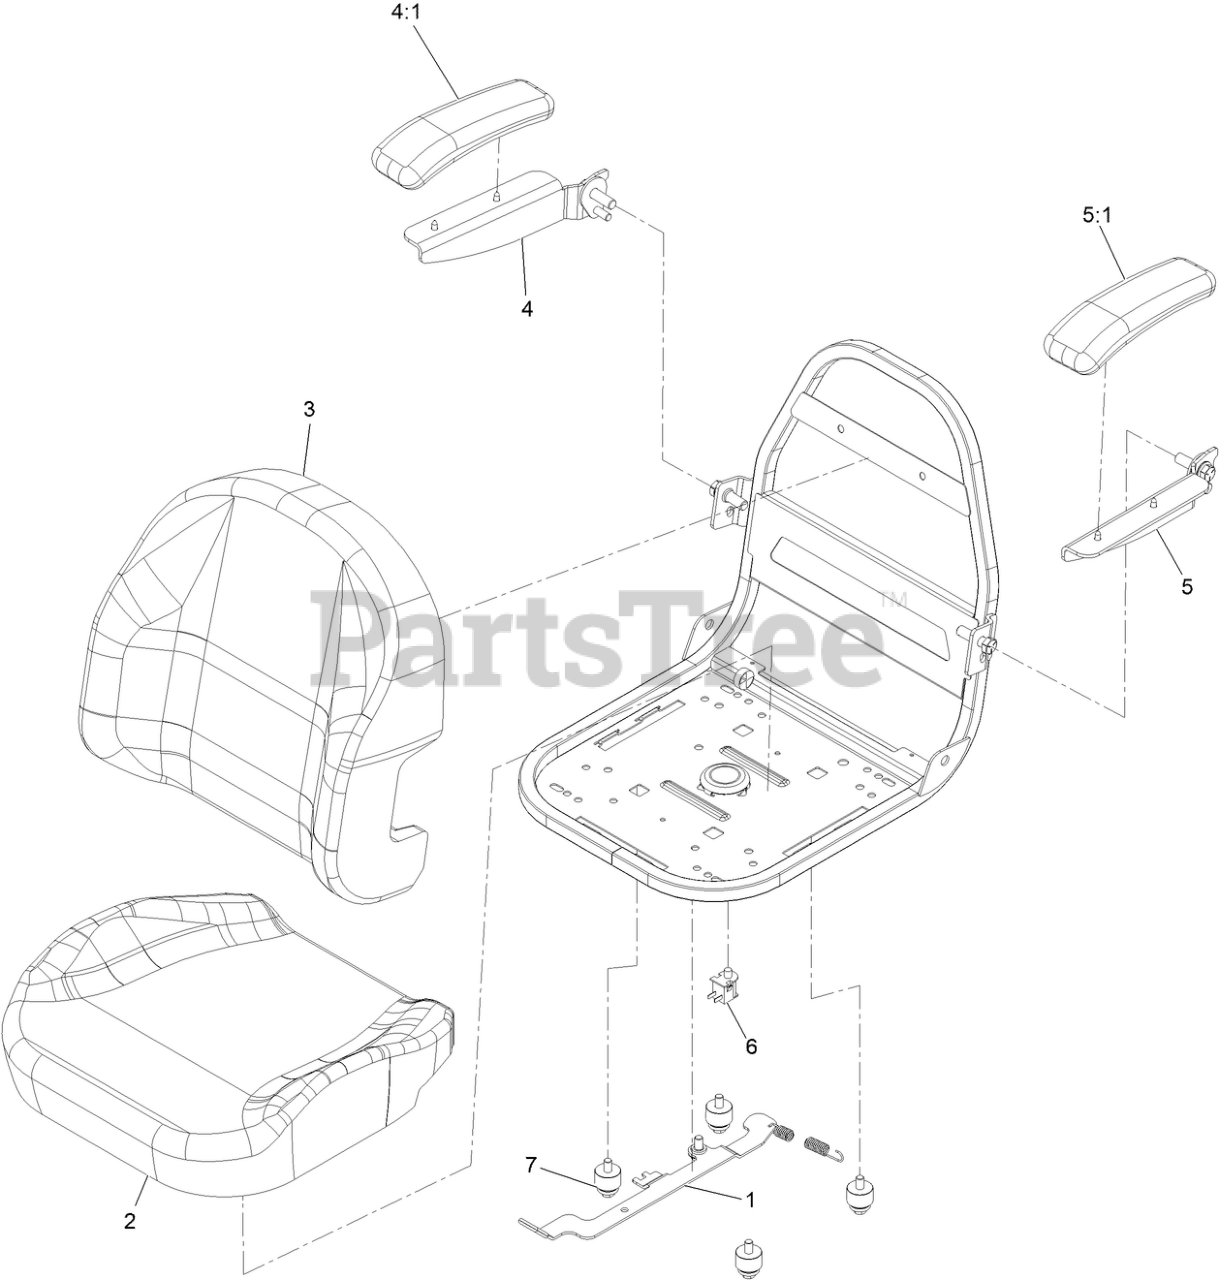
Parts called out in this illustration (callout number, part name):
1	TRACK ASM
2	Cushion-Seat Bottom
3	Cushion-Seat Back Exmark
4	RH Arm Rest Kit
4:1	CUSHION-REST, ARM
5	LH Arm Rest Kit
5:1	CUSHION-REST, ARM
6	SWITCH-BAIL
7	BUSHING ASM
